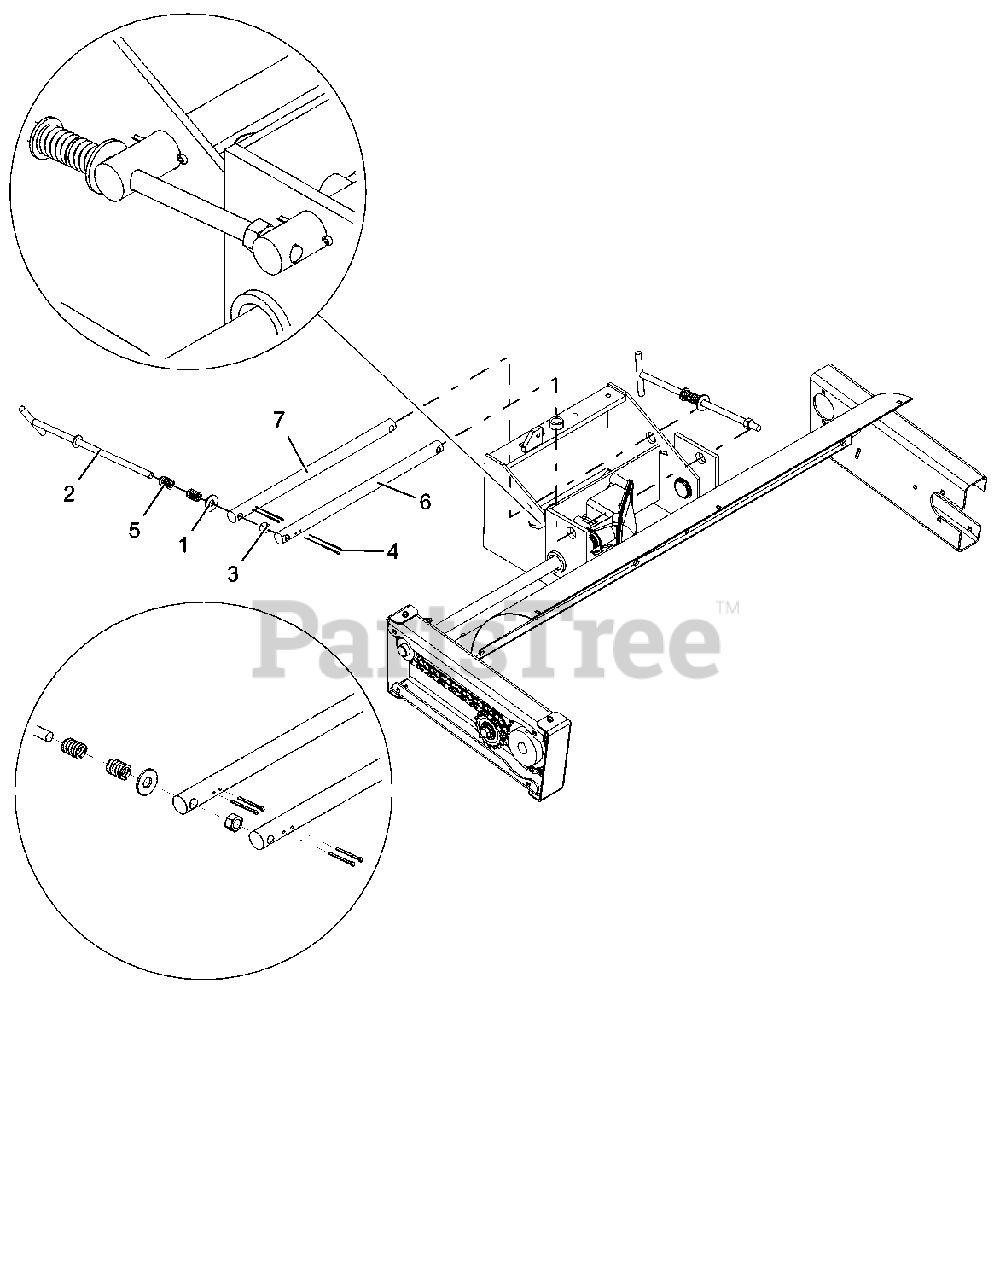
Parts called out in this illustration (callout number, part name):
1	WSHR,FL-STL.563X1.38X.109ZC120
2	WLDMT, ROD THREADED
3	NUT,HEX .50-13 G5ZC120
4	PIN,CTR.12X1.50EXTPRSQCT ZC120
5	SG-COMP .125X.78X1.00 ZC120
6	ANCHOR, ADJUSTABLE THREADED
7	ANCHOR,ADJMT
